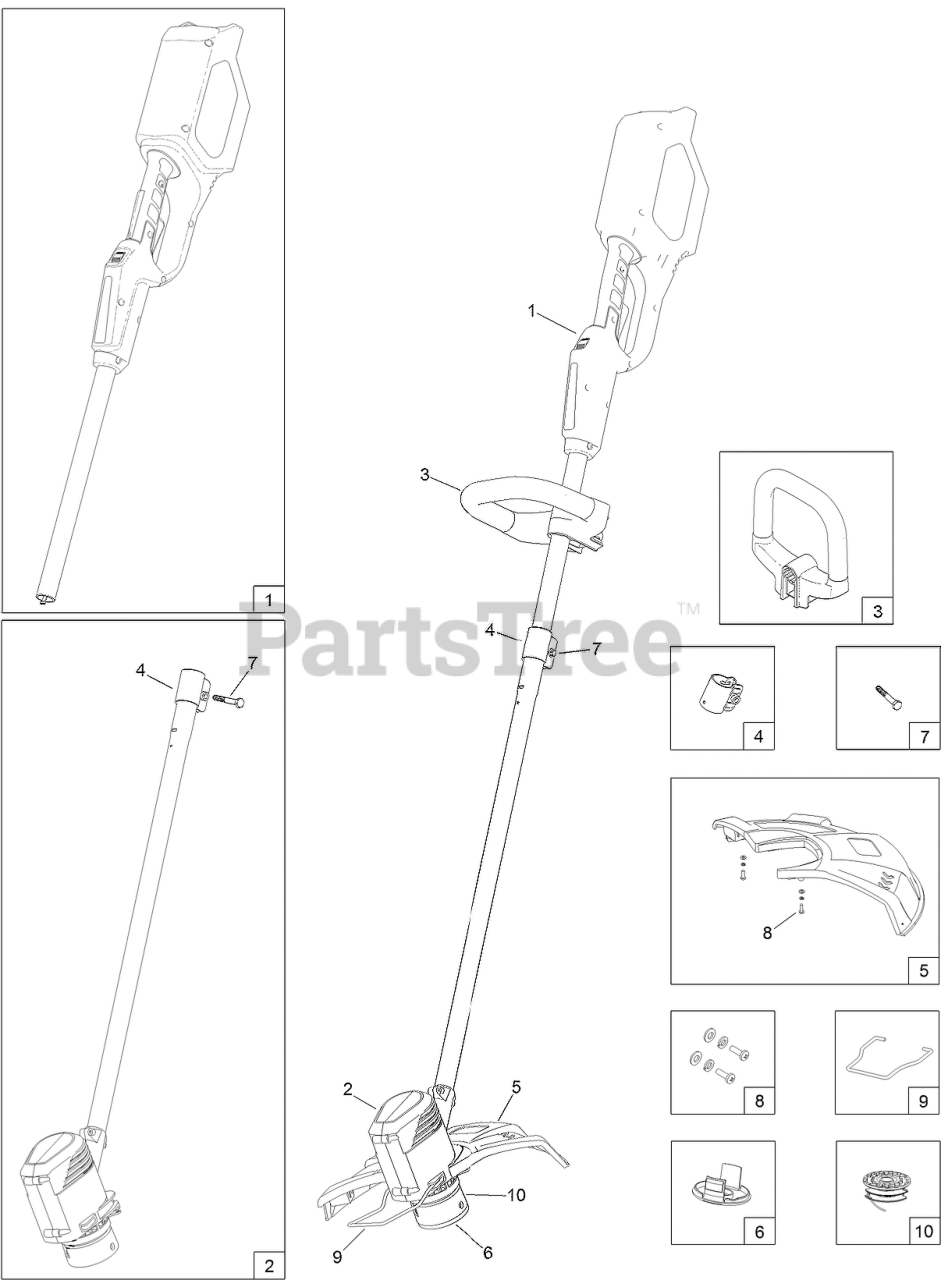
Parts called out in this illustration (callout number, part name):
1	UPPER HANDLE ASM
2	HOUSING-MOTOR, LOWER
3	HANDLE-ASSIST
4	CLAMP-CONNECTION, SHAFT
5	GRASS SHIELD ASM
6	CAP-RETAINER, SPOOL
8	SCREW WITH WASHERS ASM
9	WIRE-GUIDE, STRING TRIMMER
10	TRIMMER SPOOL-DUAL LINE, 1-PACK
